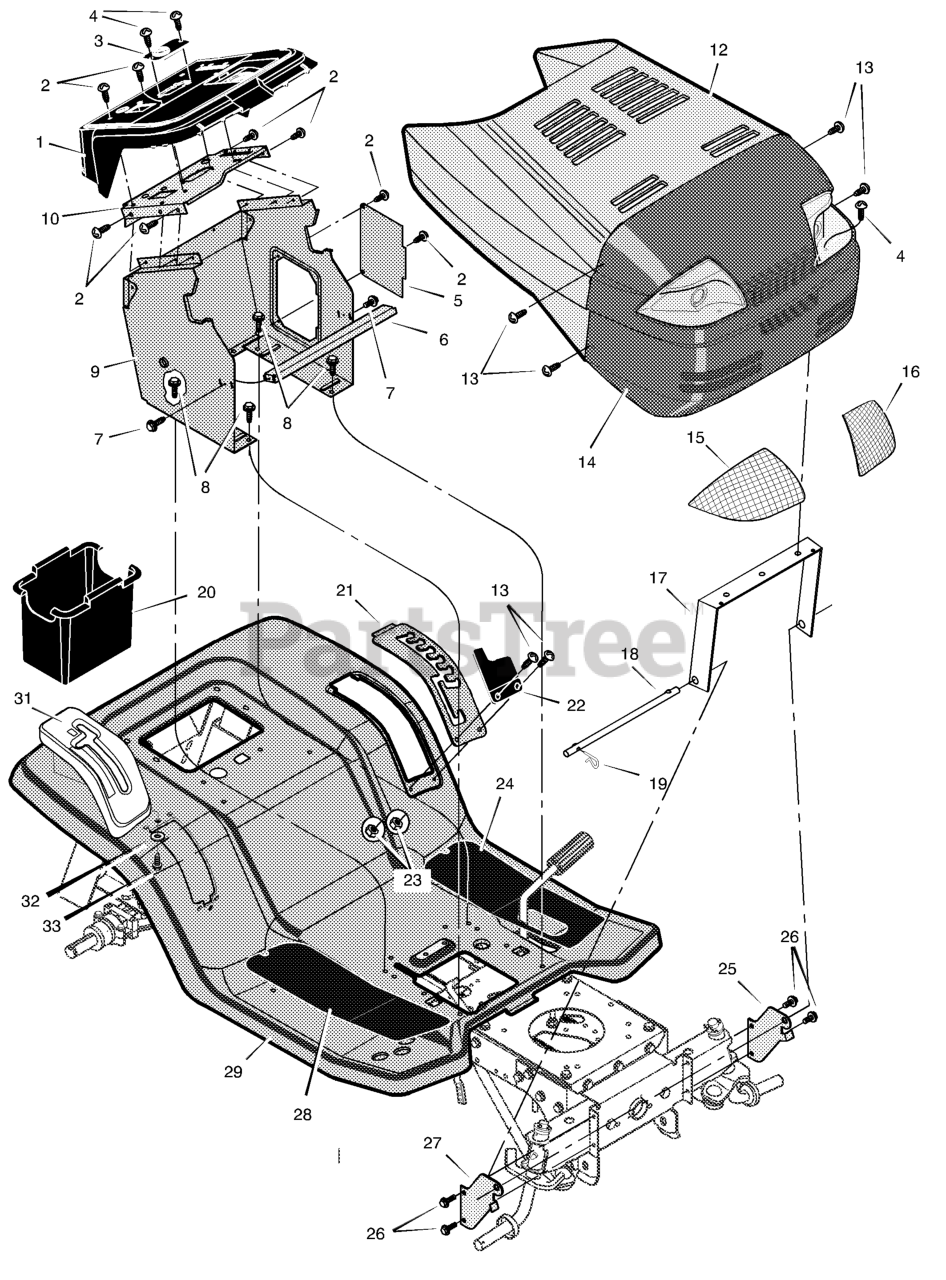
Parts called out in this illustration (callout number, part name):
2	Screw
3	Bearing, Upper Steering
5	Panel, Side Access
6	Channel, Support
9	Support, Dash
10	Plate, Dash
12	Hood
13	Bolt, Shoulder
14	Grille
15	Lens, Right
16	Lens, Left
17	Brace, Grille
18	Rod, Pivot
19	Pin, Hair
20	Container, Battery
21	Plate, Lift Detent
24	Mat, Left
25	Support, Left Grille
27	Support, Right Grille
28	Mat, Right
29	Deck, Seat
30	Decal, Left Hood
31	Cover, Shift
